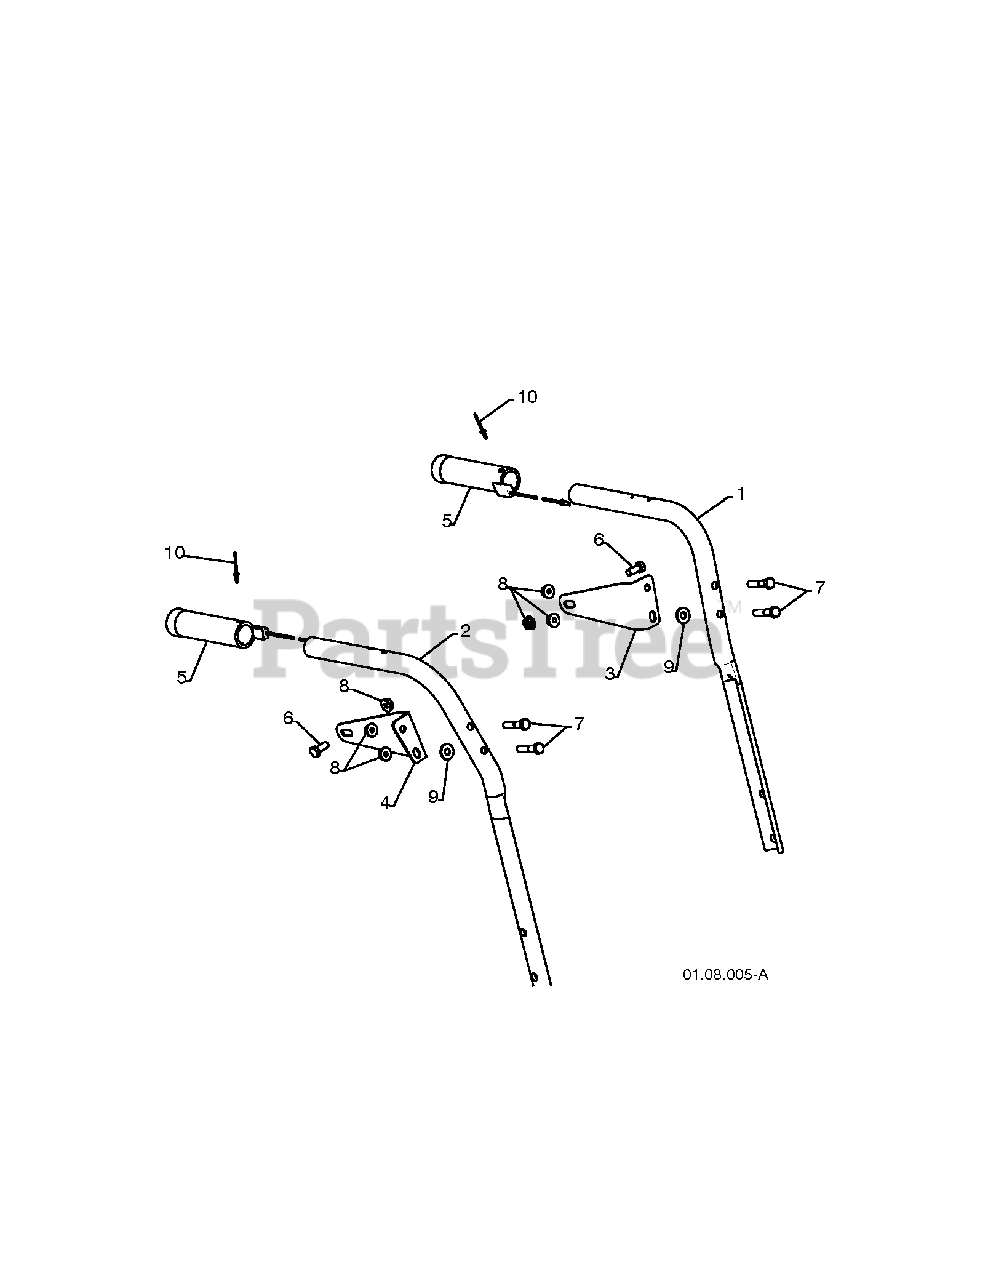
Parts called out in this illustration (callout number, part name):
1	TUBE.HANDLE.PLOW.LH.PNT
2	TUBE.HANDLE.PLOW.RH.PNT
3	BRACKET.PANEL.LH.
4	BRACKET.PANEL.RH
5	GRIP HANDLE HEATED
6	BOLT
7	HEX BOLT
8	NUT, LOCK 5/16-18
9	WASHER.20X8.5
10	RIVET.POP.1/8X
